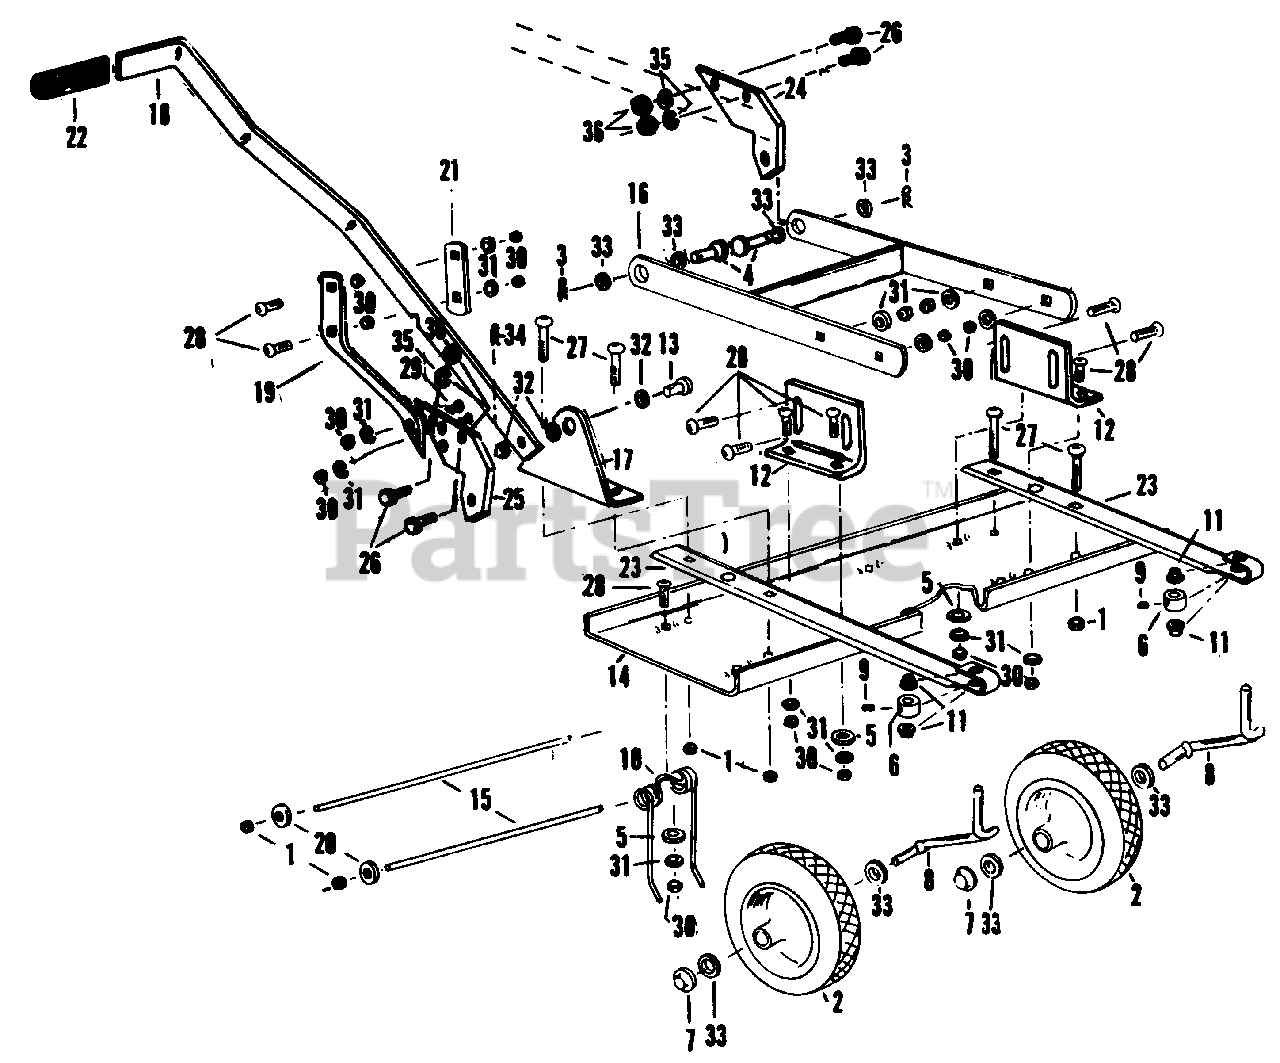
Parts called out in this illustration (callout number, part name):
1	1/4" Hex lock nut
1	FOOT, right hand
2	Gauge wheel
2	FOOT, left hand
3	1/8" Hairpin cotter
3	GUARD, FOOT POCKET, right hand
4	1/2" x 1" Clevis pin
4	GUARD, FOOT POCKET, left hand
5	5/16" Special washer
5	FRAME, FRONT PANEL
6	Locking collar
6	BRACE, FRONT PANEL FRAME
7	Push nut
7	SUPPORT, CHUTE CONTROL CRANK
8	BRACKET, REAR ATTACHING, right hand
9	5/16" Set screw
9	BRACKET, REAR ATTACHING, left hand
10	Thatching tine
10	PLATE, REAR ATTACHING
11	1/2" Nylon bearing
11	CROSS BAR, REAR
12	Tray bracket
12	POST, FRONT, right hand (straight w/screw)
13	Drilled pin
13	POST, FRONT, left hand (straight w/screw)
14	Tine tray
14	BRACE, TOP, right hand
15	Safety rod
15	BRACE, TOP, left hand
16	Main frame
16	TOP FRAME, HTS
17	Lift bracket
17	POST, REAR CORNER, right hand
18	Lift handle
18	POST, REAR CORNER, left hand
19	Lift handle support bracket
19	"L" BRACKET
20	5/16" x 1-1/2" Safety rod washer
20	3/4" LOOP
21	Short strap
21	FRONT PANEL VINYL
22	Handle grip
22	WINDSHIELD
23	Wheel support
23	DOOR, right hand
24	Chassis mounting plate
24	DOOR, left hand
25	Chassis mounting plate (with counter sink)
25	REAR CURTAIN
26	1/4" x 1" Hex bolt
26	TOP, FIBERGLASS, HTS (trim)
27	1/4" x 1-3/4" Carriage bolt
27	CRANK, CHUTE CONTROL
28	5/16" x 1" Carriage bolt
28	PARTS BAG (contents listed below)
29	5/16" x 3/4" Flat head machine screw
29	1/4"-20 LOCKNUT
30	5/16" Hex nut
30	DOOR HINGE
31	5/16" Lock washer
31	1/4"-20 x 3/4" BOLT
32	5/16" Plain washer
32	SPRING, DOOR LATCH
33	1/2" Plain washer
33	1/4" FLAT WASHER
34	1/8" Hairpin cotter
34	5/16"-18 x 1-1/2" BOLT
35	1/4" Lock washer
35	3/8"-16 LOCKNUT
36	1/4" Hex nut
36	3/8"-16 x 3/4" BOLT
